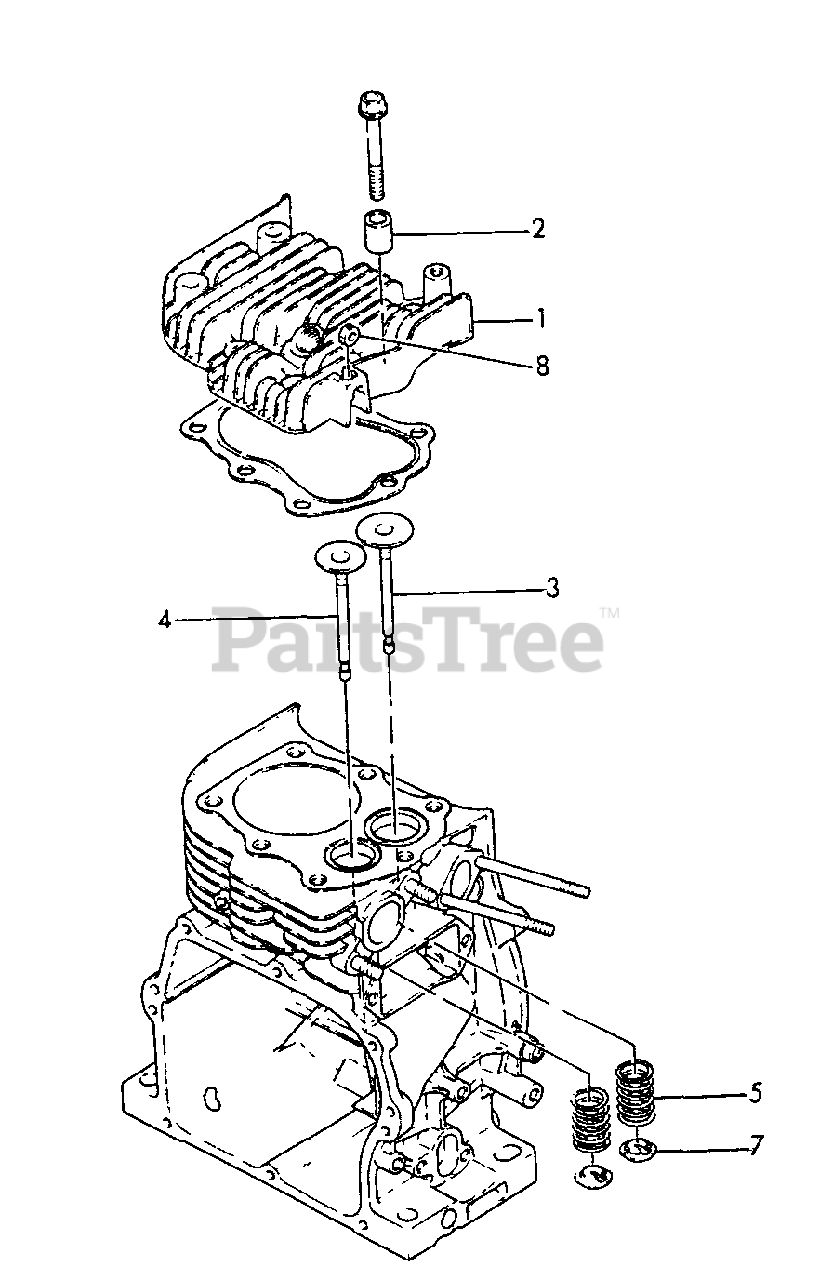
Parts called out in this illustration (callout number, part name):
1	HEAD, CYLINDER
2	SPACER
3	VALVE, INTAKE
4	VALVE, EXHAUST
5	SPRING, VALVE
7	RETAINER, SPRING
8	LOCKNUT - 6 -- PLATED
